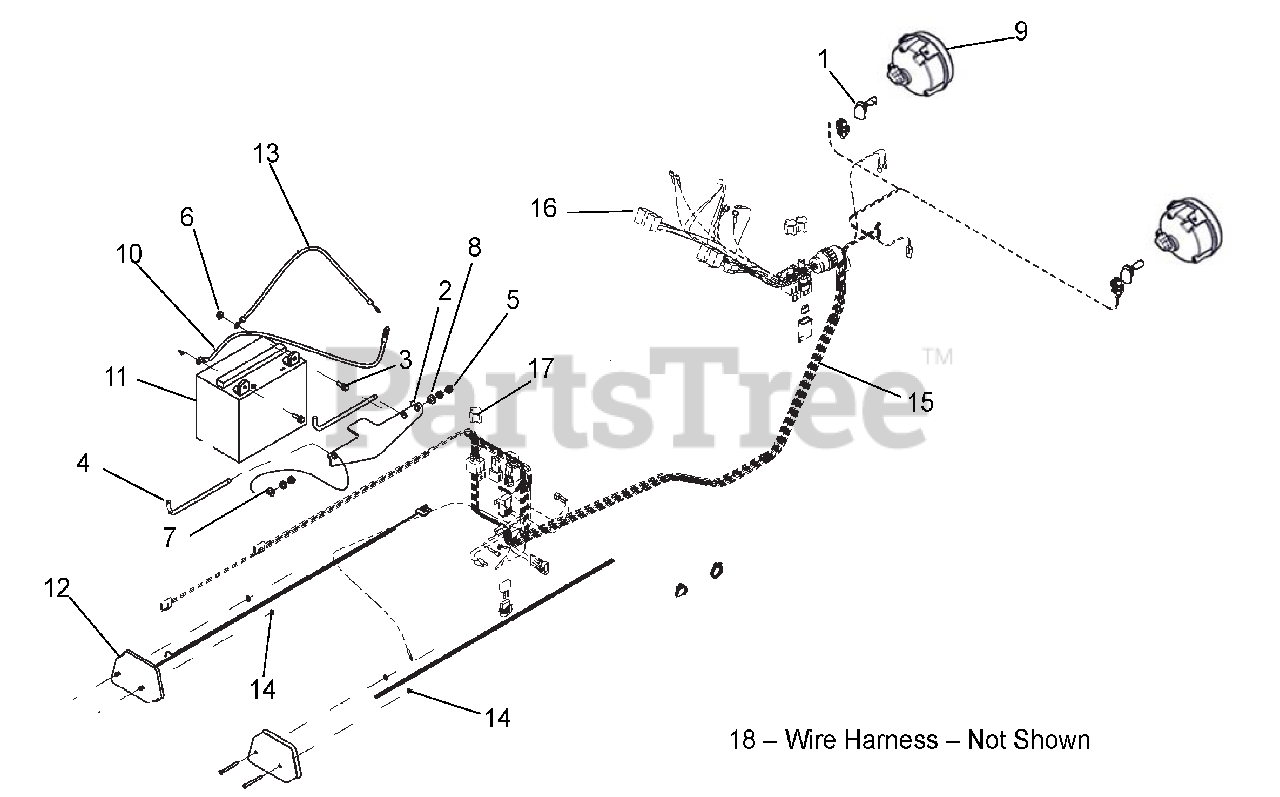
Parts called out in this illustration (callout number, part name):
2	HOLDOWN, BATTERY ST
3	SCR-HEX-FLNG .25-20 X .625 G2
4	SP HOOK 5/16-18X9X3 THREAD
5	@NUT-HEX .31-18 YWZC
6	@NUT-LK-TOP-FLG .25-20 YWZC
7	@WSHR-FL-STL.312X.734X.065 YWZ
8	@WSHR-LK .31X.078 REG YWZC
9	HEADLIGHT, ROUND
10	BATTERY CABLE POSITIVE 15 INCH
11	BATTERY
12	TAIL LIGHT, LED
13	20" 6GA NEGATIVE BLACK CABLE
14	PUSH RETAINERS 4 NON-THRD SHFT
15	HARNESS, MAIN
16	HARNESS, SUB DASH
17	RELAY, ISO MINI ELEC.
